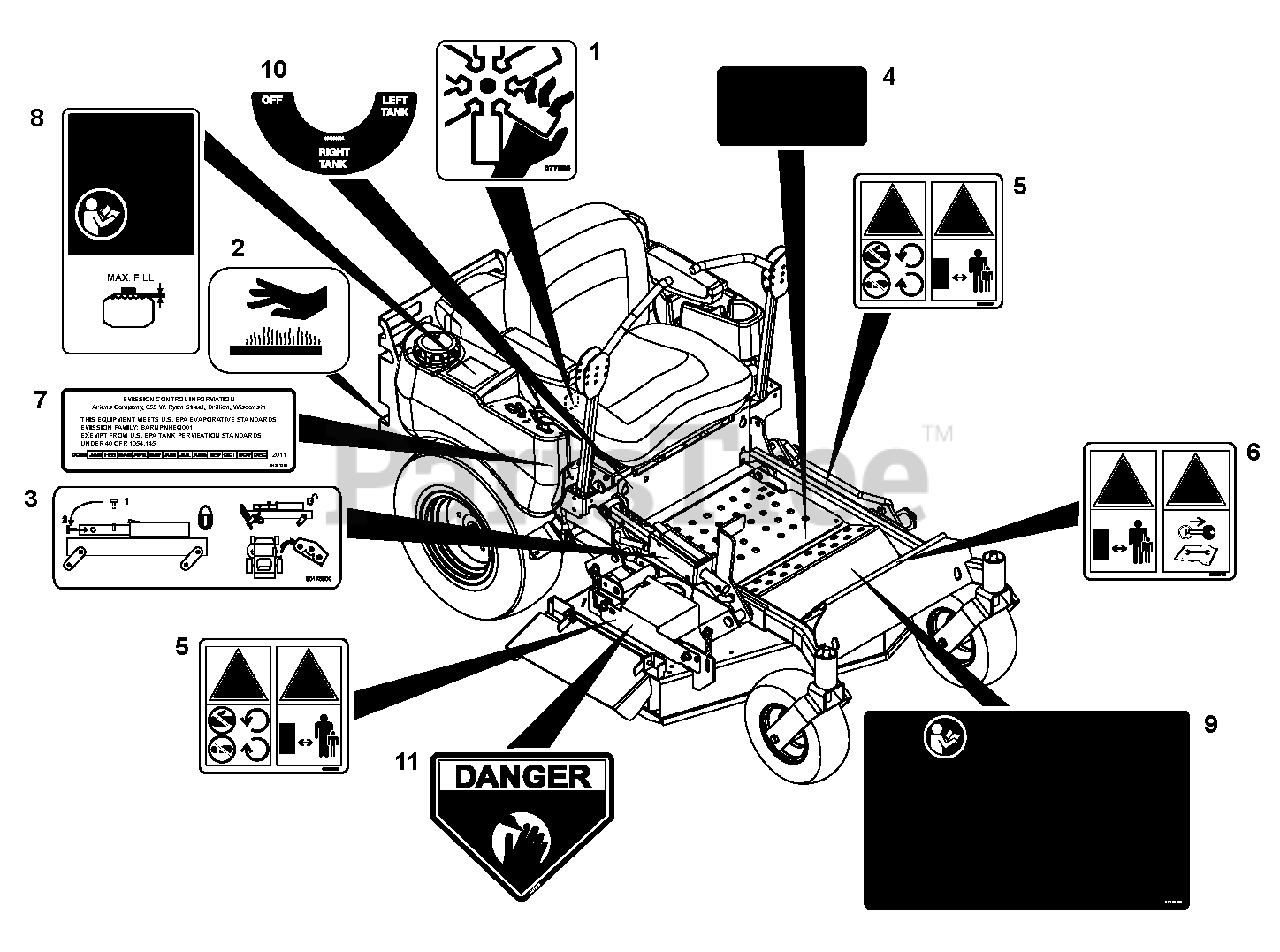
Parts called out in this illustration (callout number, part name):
1	Decal, Danger Fan
2	Decal, Hot Surface
3	Decal, Deck Service
4	Decal, Safety, Guarding
5	Decal, CE Deck
6	Decal, CE Caution
7	Label, EPA Non-Compliant Tank
8	Decal, Fuel Warning
9	Decal, Main Safety, Commercial
10	Decal, Fuel Valve
11	Decal, Danger
